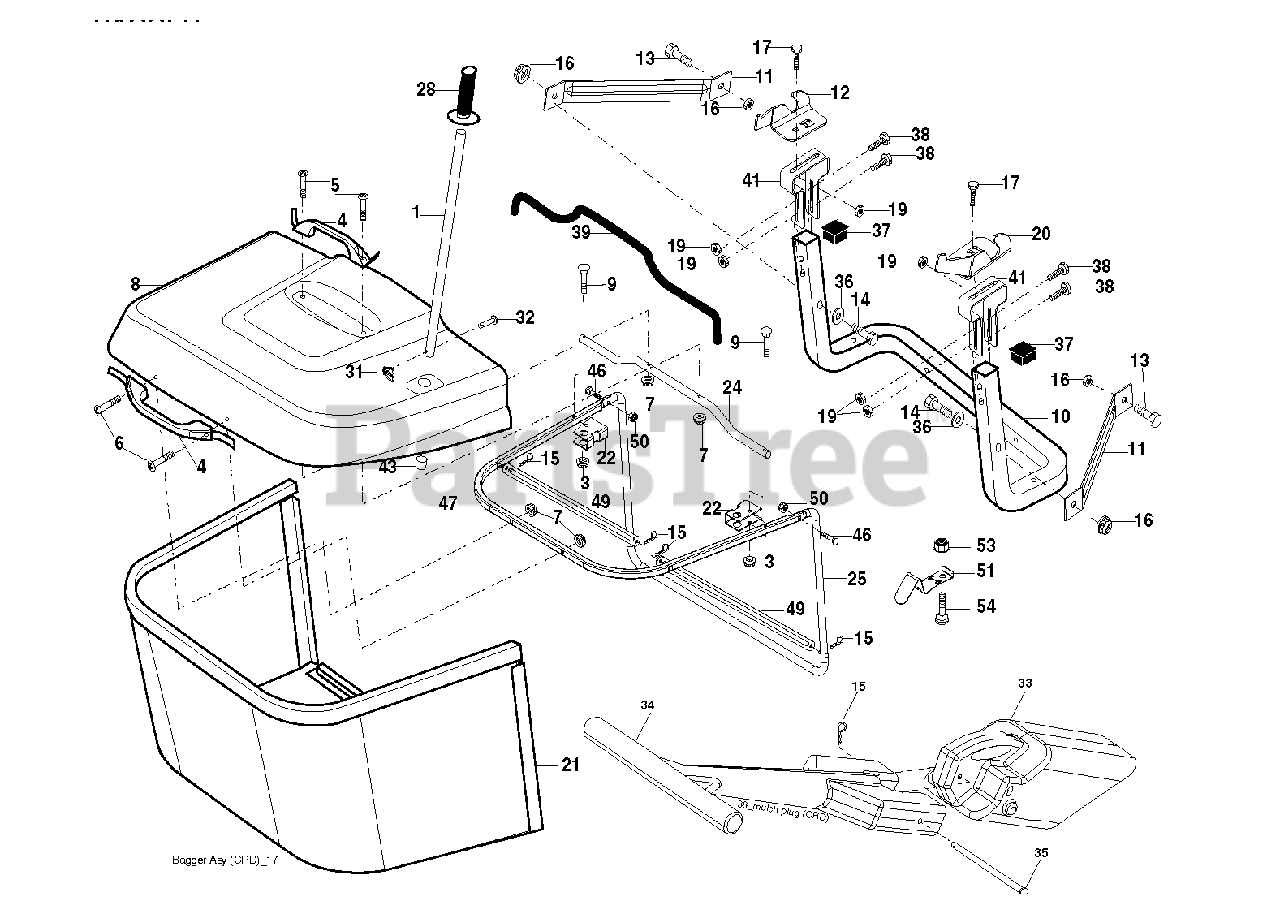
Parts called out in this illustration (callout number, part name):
1	TUBE.PNT.HDL.BAGGER.
3	NUT T
5	SCREW.PAN.HEAD
11	BRACKET
14	BOLT-HEX EAK
15	RETAINER-SPRNG RB
16	NUT LOCK FLG 3/8-16 UNC
17	BOLT
19	NUT LOCK HEX FLANGE 5/16-18
20	BRKT.PIVOT.RH.CRD
21	BAGGER.ASM.CRD.2007
22	BRACKET.BAGGER.SD.
24	TUBE
28	GRIP.HANDLE.BLACK
31	RETAINER CLIP
32	RIVET,DRILLED
33	MULCHING.PLUG.1078.CRD.NON-TEX
35	PIN
38	BOLT.5/16-18X2.5
39	SEAL.BAGGER.CRD
41	BRACKET.BAGGER.SD.
43	PLUG, TUBING END
46	BOLT.CARRIAGE.5/16-18
50	NUT.71038.31-18.HEX.NYLOCK
53	NUT
54	BOLT
